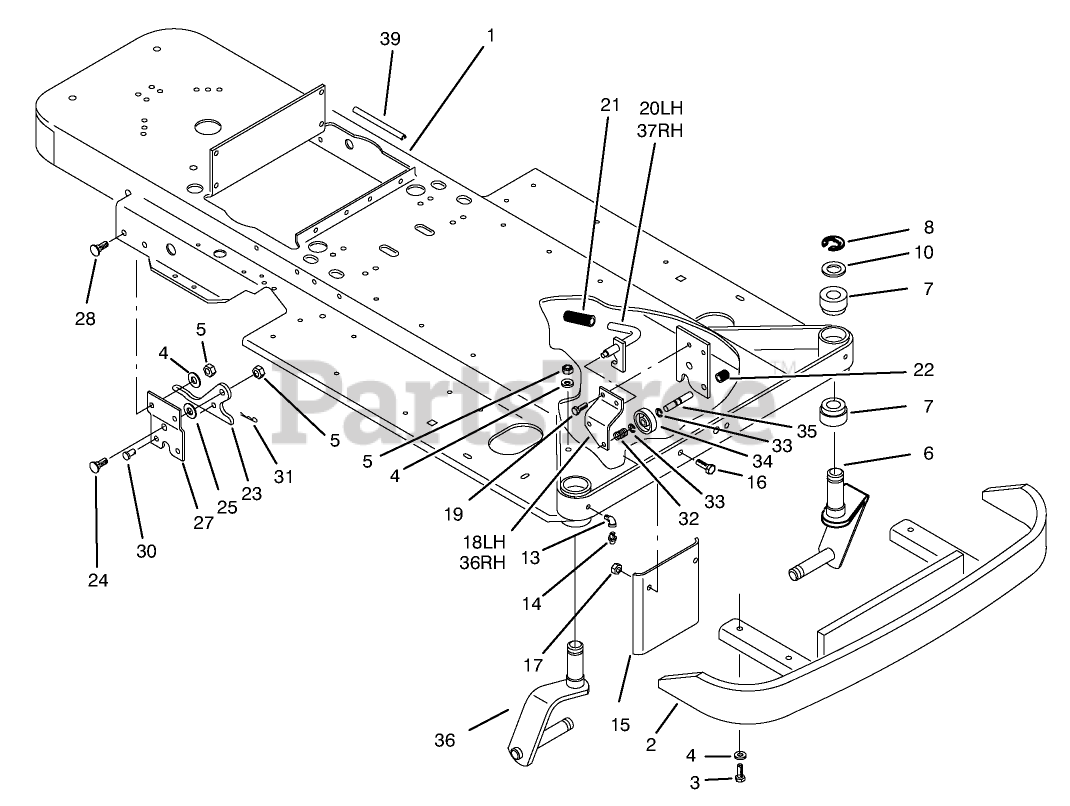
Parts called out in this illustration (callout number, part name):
1	WLDMT-FRAME
2	BUMPER WELDMENT
3	SCREW-HH
4	WASHER-FLAT
5	NUT-LOCK, NI
6	L/H SPINDLE WA
7	BUSHING PIVOT
8	RING-RETAINING
10	Washer
11	BRKT LATCH RH
13	ELBOW
14	FITTING-GREASE
16	SCREW-HH
17	NUT-LOCK, NI
18	BRKT LATCH LH
19	SCREW-HWHTF
20	WLDMT-LATCH L.H.
21	GRIP
22	CAP-ROD, PLUNGER
23	PLATE-LATCHING
24	BOLT-CARR
25	WASHER
27	PLATE-HITCH(NS)
28	BOLT-CARR
30	PIN-CLEVIS
32	SPRING
33	RING-RETAINING
35	ROD-LOCK
36	R/H SPINDLE WA
37	WLDMT-LATCH R.H.
38	PIN-HAIR
39	EDGE TRIM
